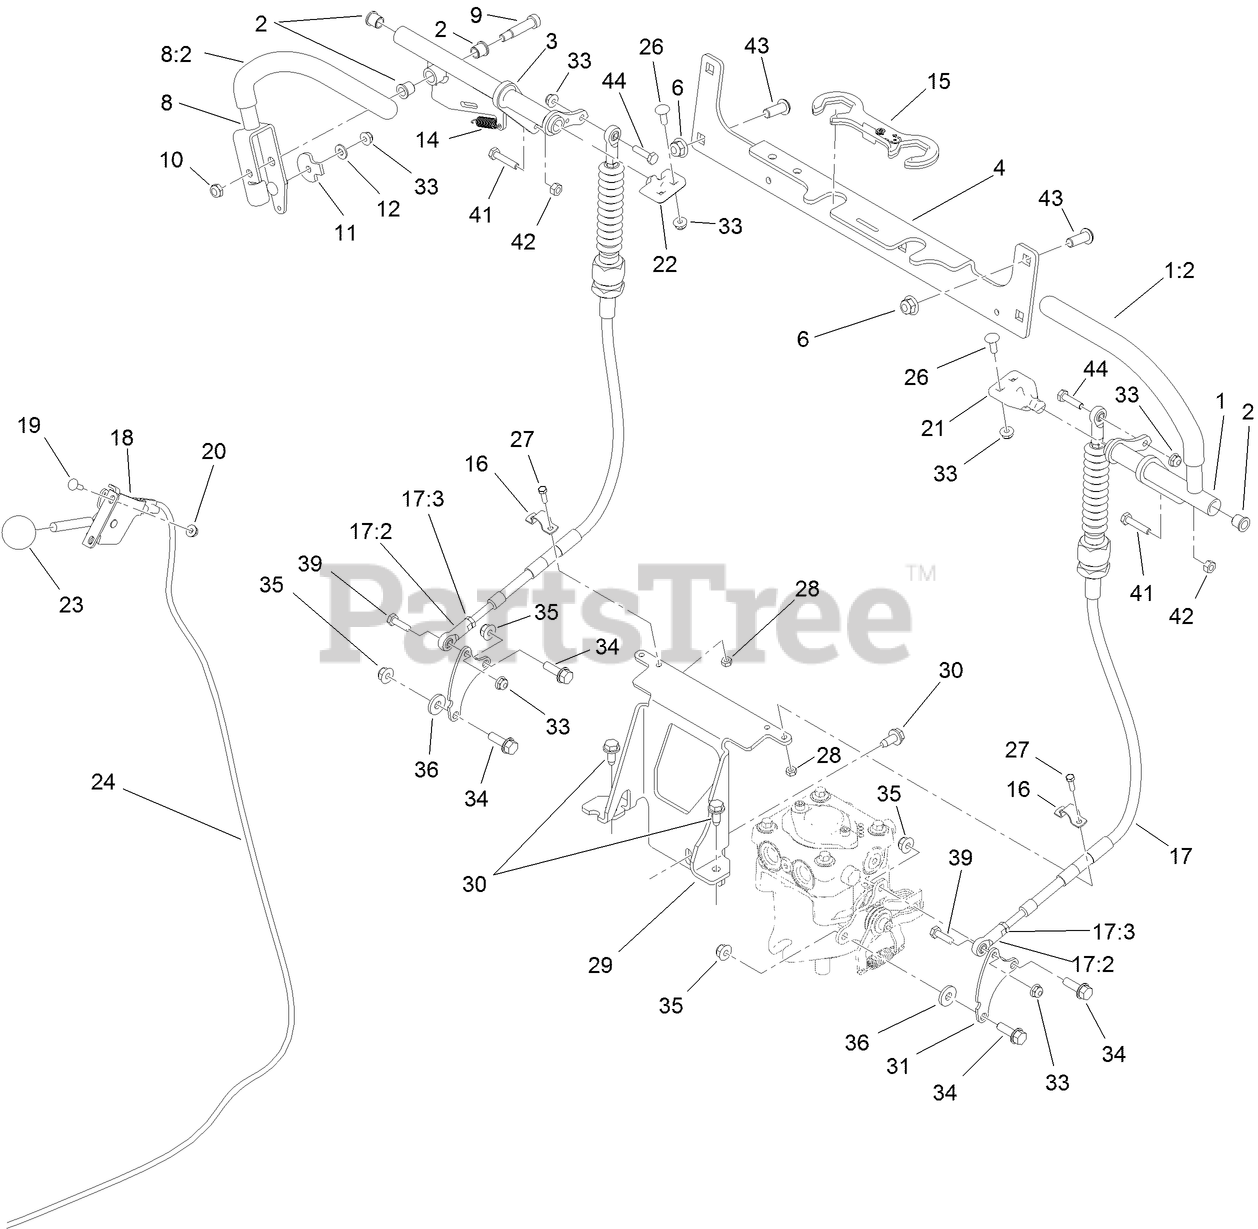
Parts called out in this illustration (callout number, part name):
1	LH LEVER ASM
2	BEARING
3	CONTROL-MOTION, RH
4	BRACKET-CROSS
6	NUT-HF, NI
8	LEVER-MOTION, RH
9	SCREW-HSH
10	NUT-LOCK, NI
11	CAM-LEVER
12	WASHER-FLAT
14	SPRING-EXTENSION
15	LOCK-CABLE
17	CABLE ASM
17:2	ROD END-BALL JOINT
17:3	NUT-JAM
18	LEVER-CONTROL
19	BOLT-CARR
20	NUT-LOCK, FLANGE
21	TAB-PIVOT, LH
22	TAB-PIVOT, RH
23	KNOB-BALL
24	CABLE-THROTTLE
26	BOLT-CARR
28	NUT-LOCK, NI
29	BRACKET-MOUNT, CABLE
30	SCREW-HWHTF
31	PLATE-CONTROL, PUMP
33	NUT-HF
34	SCREW-HHF
35	NUT-HF, NI
36	WASHER-FLAT
39	SCREW-HH
41	SCREW-HH
42	NUT-HEX
43	SCREW-HSBH
44	SCREW-HH
